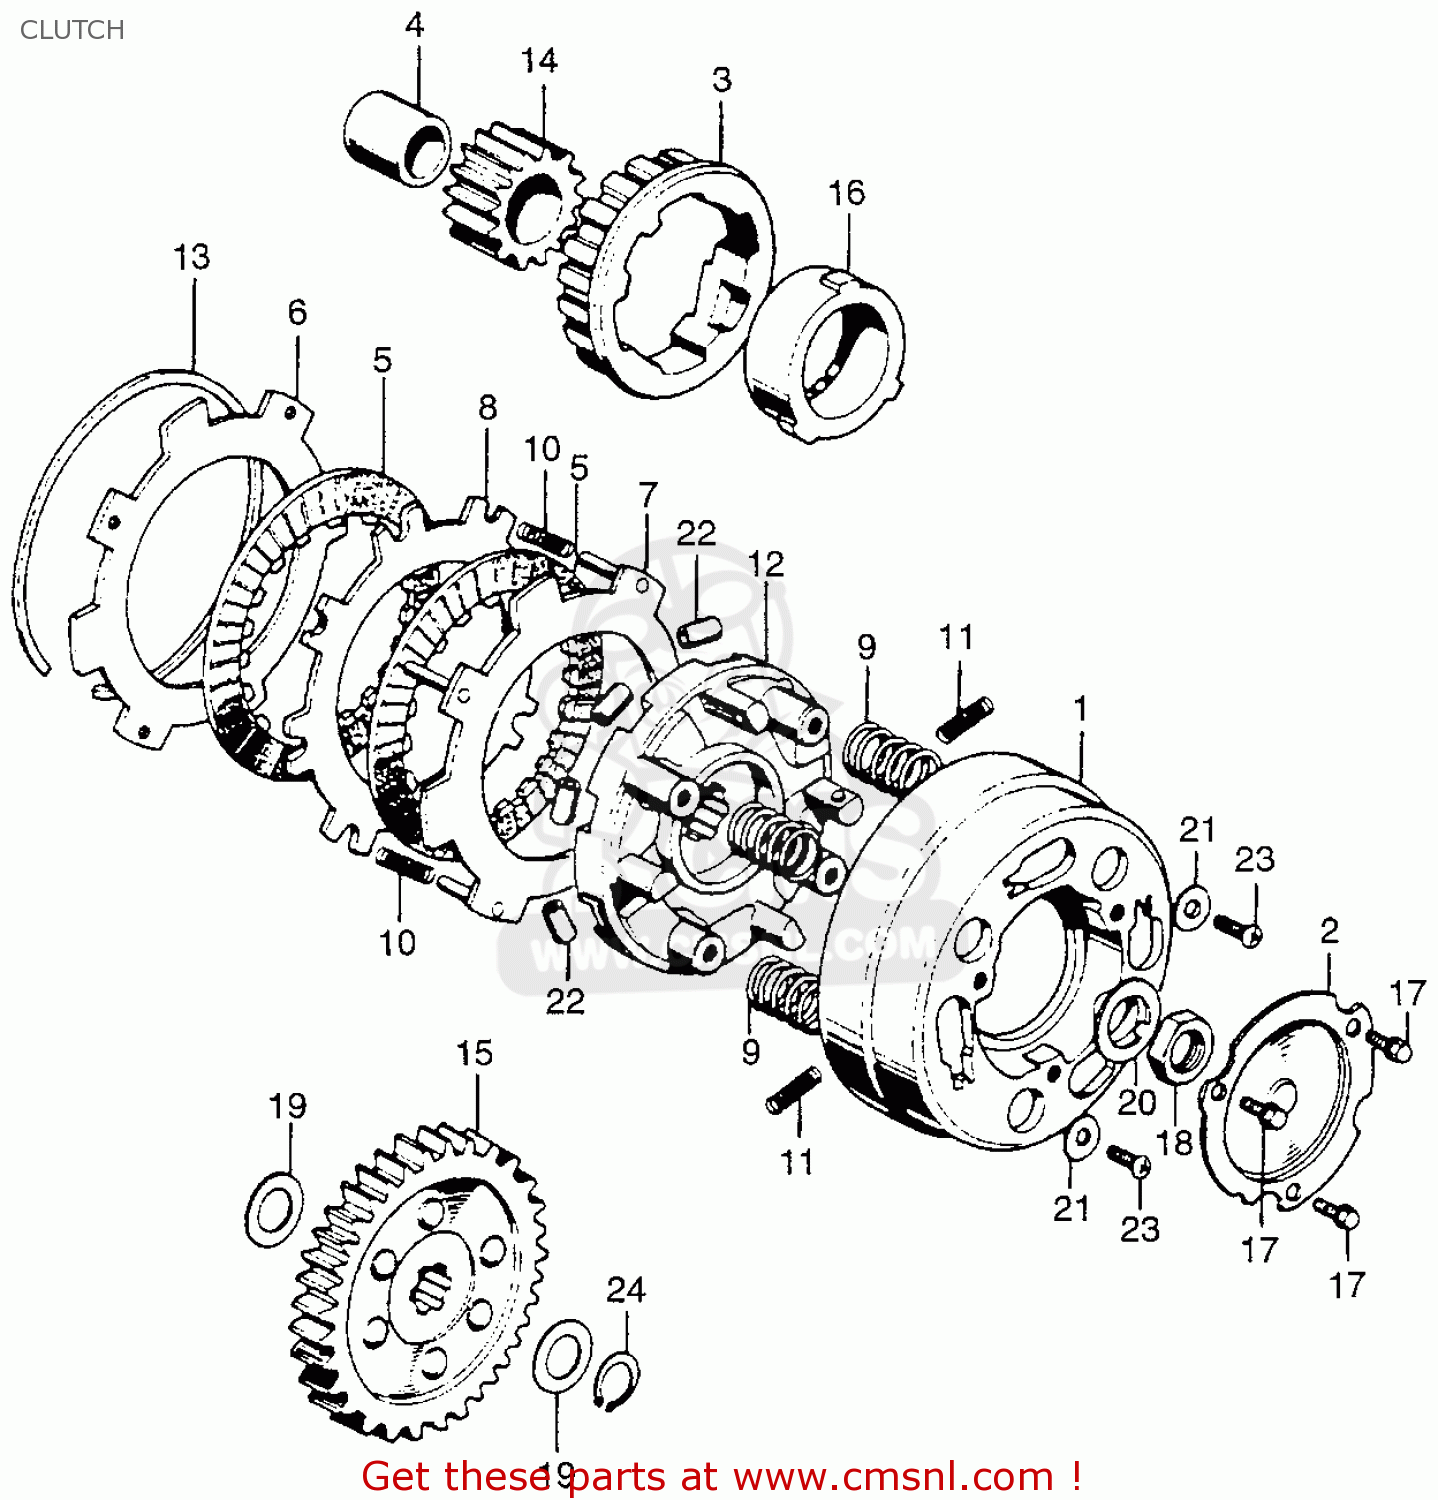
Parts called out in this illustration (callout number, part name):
1	OUTER CLUTCH
2	CVR, CLUTCH (OUTER)
3	CENTER,CLUTCH
4	GUIDE, CLUTCH CENTER
5	DISK.CLUTCH.FRICT (NAS)
6	PLATE,CLUTCH
7	PLATE B,CLUTCH
8	PLATE C,CLUTCH
9	SPRING,CLUTCH
10	SPRING,CLUTCH
11	SPRING, CLUTCH
12	PLATE,DRIVE
13	SET RING,101.5M/M
14	GEAR, DRIVE
15	GEAR (54T)
16	OUTER,DRIVE GEAR
17	BOLT,CLUTCH OUTER
18	NUT,LOCK,14MM
19	WASHER TOP GEAR
20	WASHER,LOCK,14MM
21	WASHER, STOPPER
22	ROLLER 8X10
23	SCREW,CROSS 5X8
24	CIRCLIP,17MM
